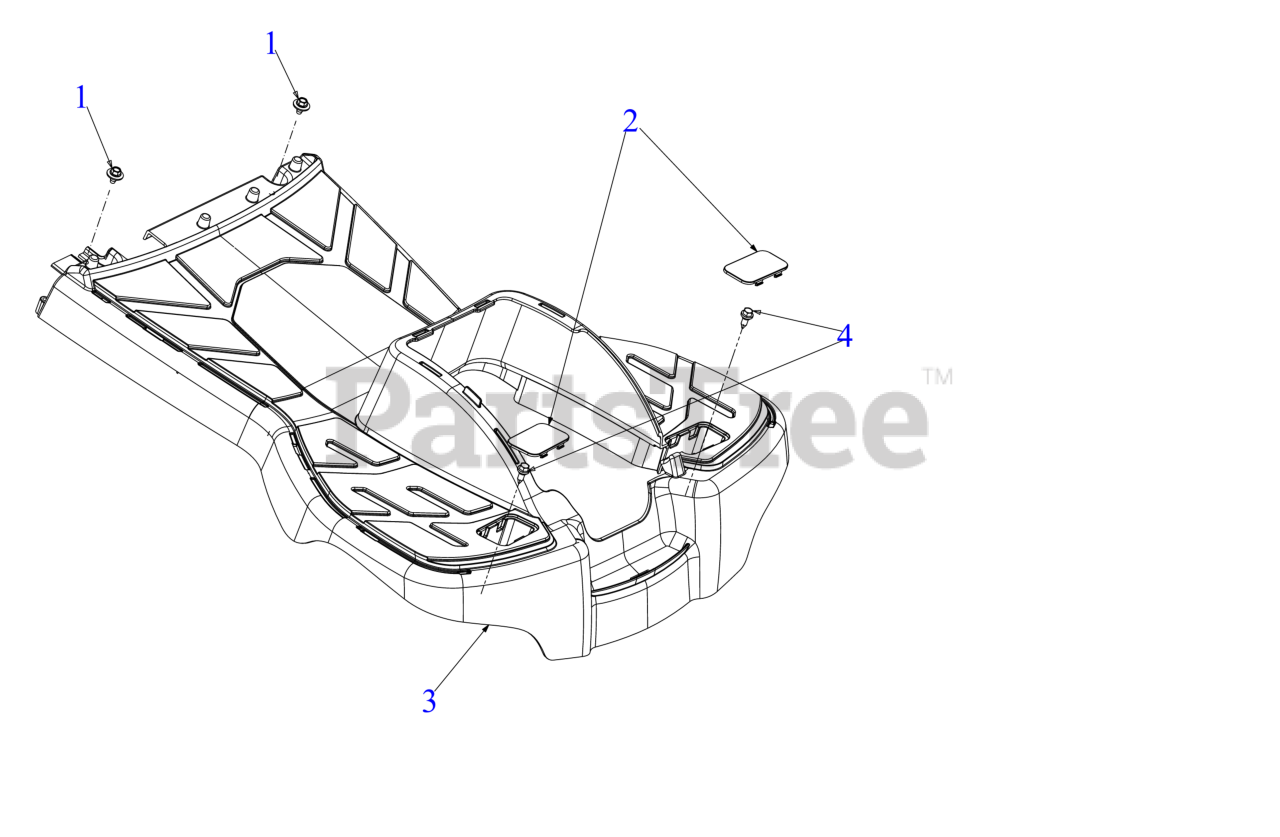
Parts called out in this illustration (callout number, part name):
1	SCREW 1/4-20 x .50
2	RUNNING BOARD PLUG
3	RUNNING BOARD NO RMC
4	SHOULDER SCREW
